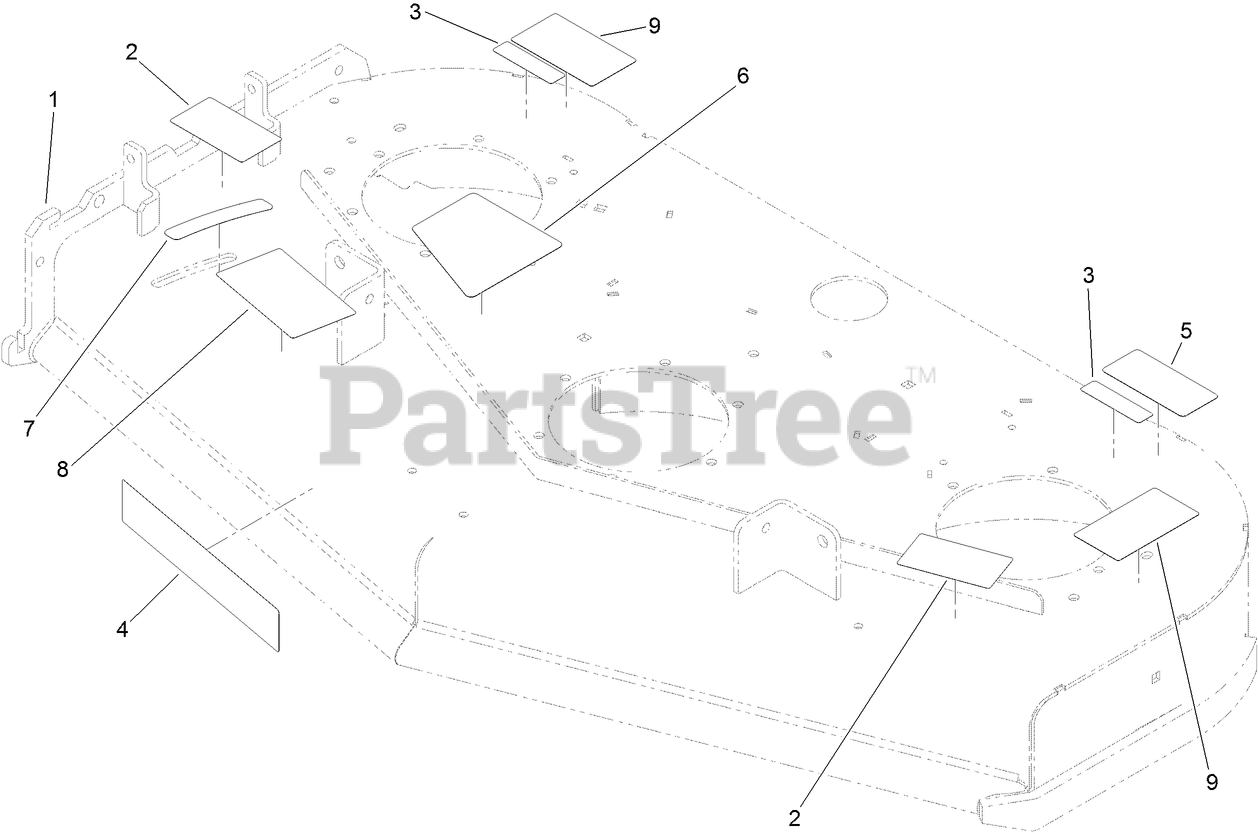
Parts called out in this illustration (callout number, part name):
1	DECK ASM
2	DECAL-DANGER
3	DECAL-DANGER
5	DECAL-TORQUE, BLADE BOLT
6	DECAL-BELT TENSION, CE
7	DECAL-SETTING, BAFFLE
8	DECAL-ADJUSTMENT, BAFFLE
9	DECAL-DANGER, ROTATING PARTS
